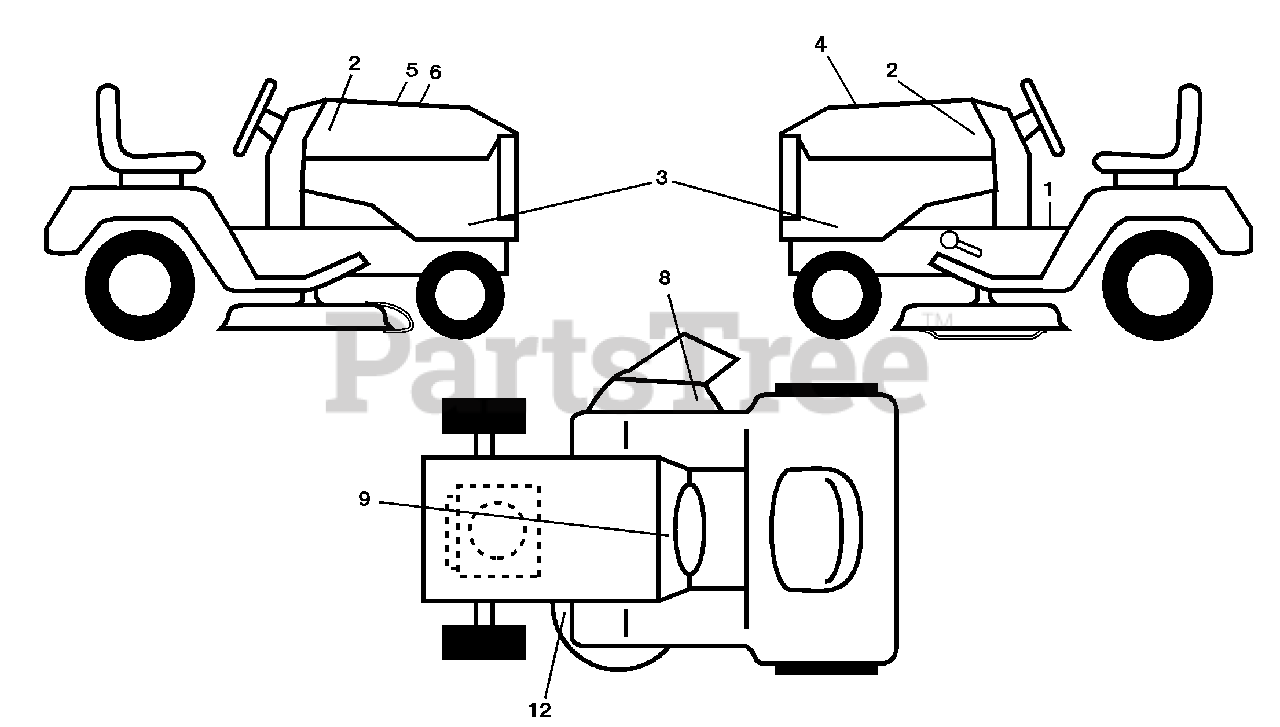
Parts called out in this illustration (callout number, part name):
1	Decal, Operators
2	Decal, Hood
3	Decal, Emblem Panel SD
4	Decal, Engine
5	Decal, Customer Respons.
6	Decal, Replacement
8	Decal Mower Warn Keep Hand away
9	Decal, Battery Dnge/Poi
12	Decal, Mower V-Belt Schematic
